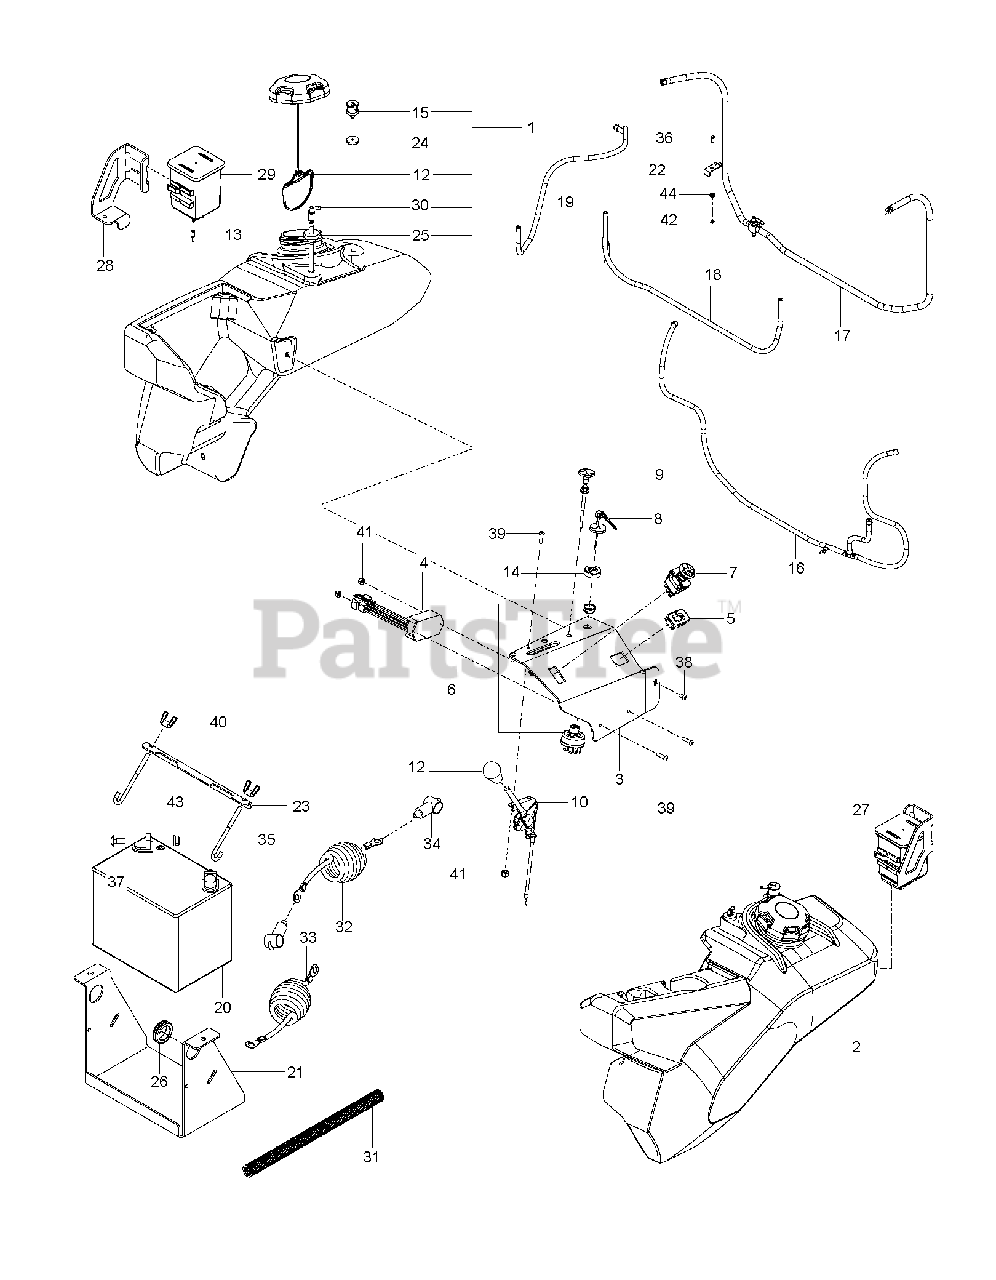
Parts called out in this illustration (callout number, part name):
1	FUEL TANK ASM RH GRAY PZ
2	FUEL TANK LH PZ GRAY
3	PANEL.CONTROL.GAS.GRAY
4	TIMER, SEAT
5	GUAGE.SRVCMNDR.HRMTR.
6	SWITCH, IGNITION, INDAK
7	RP SWITCH.PTO.TERMINAL.STD.RED
8	KEY, IGNITION
9	CABLE, CHOKE, 48"
10	CABLE, THROTTLE, 46"
11	KNOB - SHIFT
12	CAP, FUEL
13	CAP, VINYL
14	CAP IGNITION NUT
15	VALVE.FUEL.CHECK
16	ASSEMBLY, VAPOR LINE
17	ASSEMBLY, FUEL LINE
18	HOSE CLAMP
19	CLAMP, HOSE
20	BATTERY, 12 V 330 AMP
21	BRACKET, BATTERY, BLK
22	BRACKET,FUEL VALVE, BLACK
23	BRACKET, BATTERY MOUNT
24	GROMMET, CHECK VALVE
25	RUBBER GROMMET
26	RUBBER GROMMET
27	MOUNT, CANISATER, RT
28	MOUNT, CANISTER, LT
29	CANNISTER, CARBON
30	FITTING, FUEL
31	LOOM, SPLIT, CONVOLUTED
32	CABLE, POSITIVE, 55"
33	CABLE, NEG, 55"
36	HCS 1/4C X 3/4 HCS
37	BOLT 5/16-18 X3/4 ZN/YEL GR 5
38	SCR #10-24 X 3/8 SKT HD BLK OX
39	SCR #10-24 X .75 SKT HD BLK
40	WING NUT 1/4
41	NUT 10-24 NYLOC
42	JAM NUT 1/4C (2 2 PW01)
43	5/16-18 NYLOC FLANGE NUT
44	WASHER 1/4 FLAT
